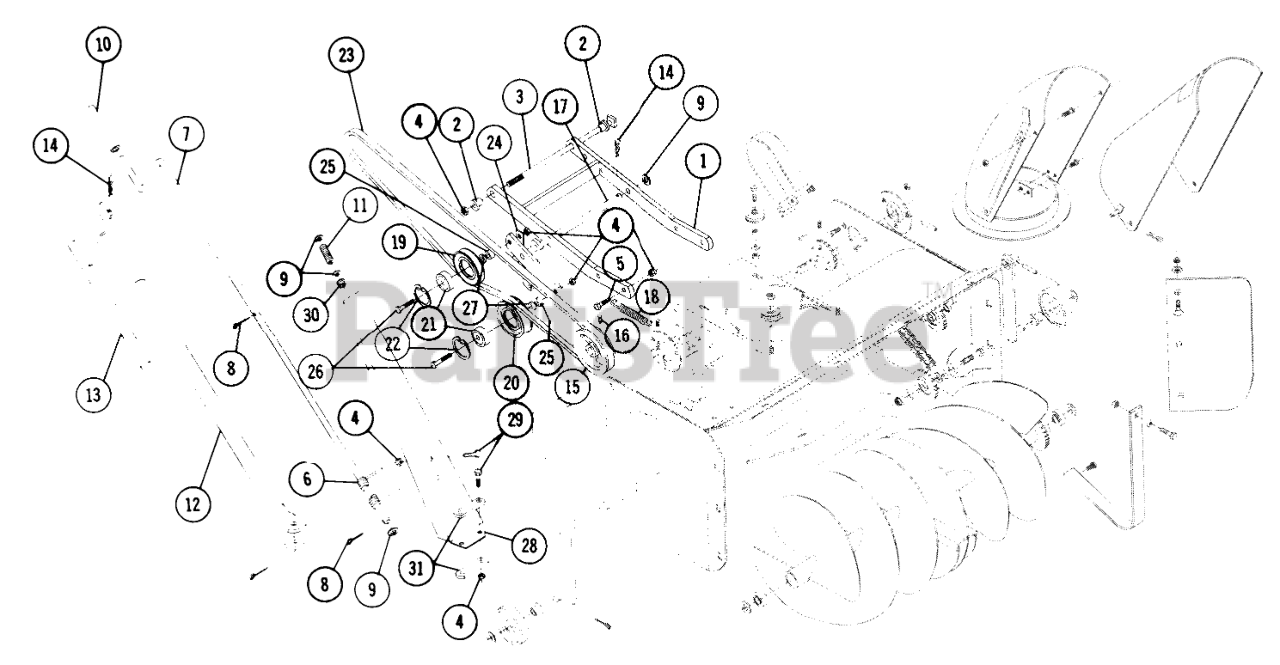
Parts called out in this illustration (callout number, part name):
1	Mounting Frame
2	Spacer
3	Bolt-Hex. 3/8-16 x 8 1/2
5	Bolt 3/8-16 x 7/8
6	Cable
7	Crank
8	Cotter Pin
9	Washer
10	Tube
11	SPRING-COMPRESSION
12	Ass-y. Tube & Bar
13	Lid Rod
14	Hairpin
15	Pulley
16	Set Screw
17	Idler Arm Ass-y
18	SPRING R
19	PULLEY IDLER
20	PULLEY IDLER
21	BEARING
22	INTERNAL SNAPRING
23	BELT
24	Bracket-Belt Guide
25	Spacer
26	Bolt Hex 3/8-16
27	Spacer
28	Crank Support
29	Bolt 3/8-16 x 3/4
30	NYLINER BUSHING
31	Bar-Reinforcing
